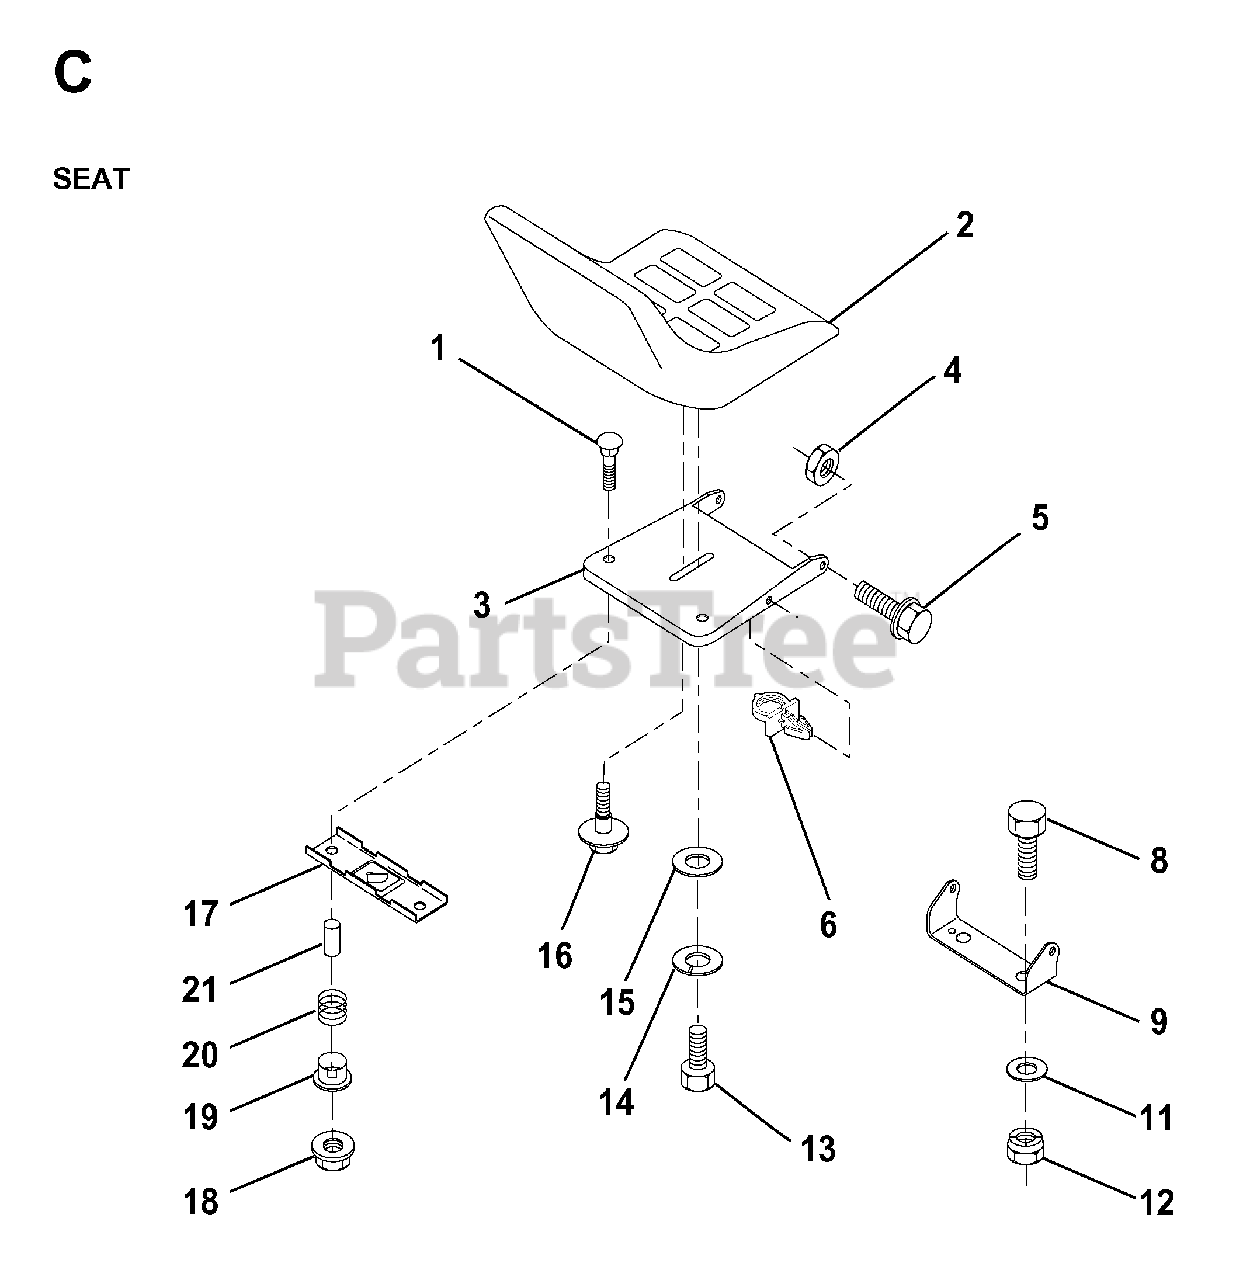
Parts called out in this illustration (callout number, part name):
1	BOLT.ROUND.HEAD.SQUARE.NECK
2	SEAT
3	PAN, SEAT
4	NUT.71038.31-18.HEX.NYLOCK
5	BOLT SHOULDER 5/16-18
6	PUSH CLIP
8	BOLT
9	SEAT PIVOT BRKT
11	WASHER 12/32X2X10GA
12	NUT
13	BOLT
14	LOCKWASHER
16	BOLT,SHOULD
17	BRKT SWITCH
18	NUT T
21	SPACER SPLIT 28X.96
